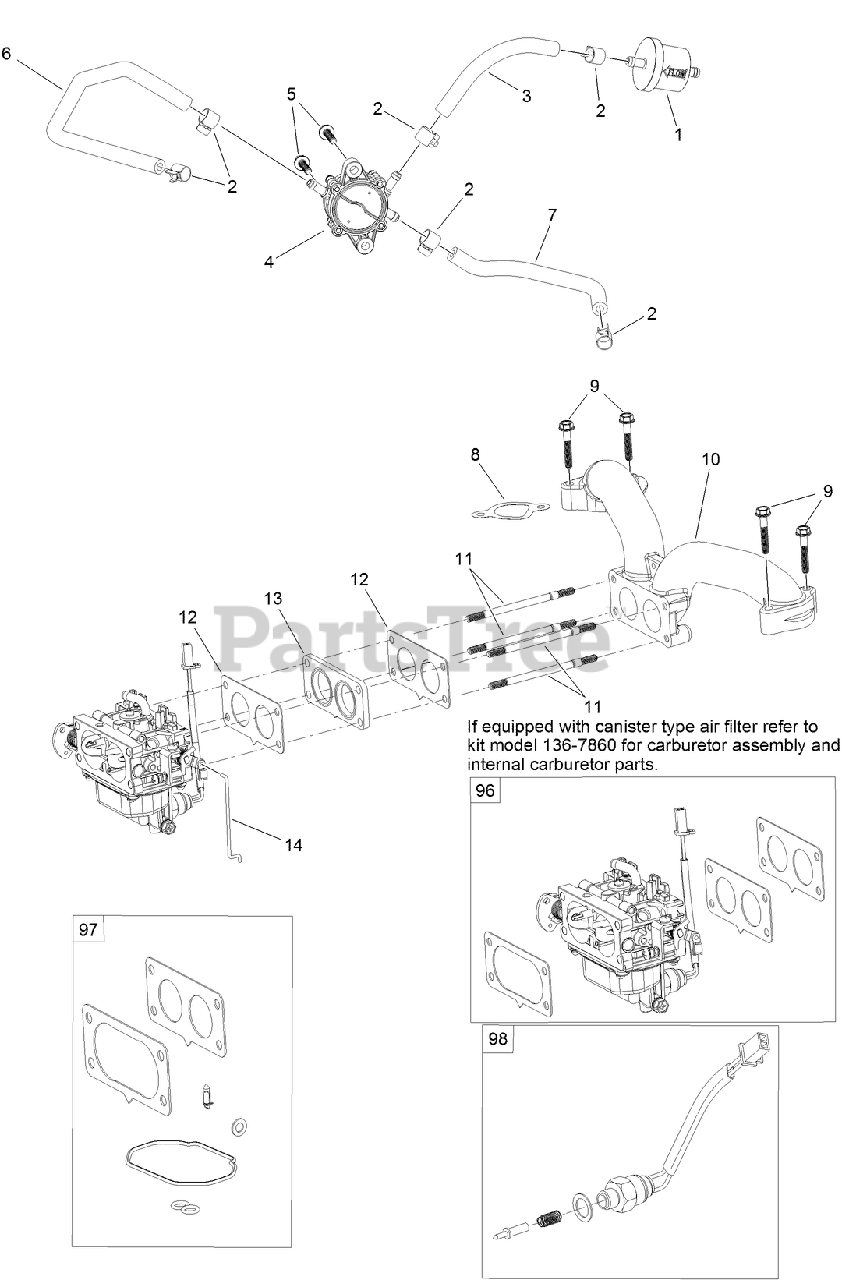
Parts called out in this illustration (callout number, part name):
1	FILTER-FUEL
2	CLAMP-FUEL LINE
3	LINE-FUEL
4	PUMP-FUEL
5	SCREW-HHF
6	HOSE-FUEL
7	HOSE-FUEL
8	GASKET-INTAKE
9	SCREW-HHF
10	MANIFOLD-INTAKE
12	GASKET-CARBURETOR
13	INSULATOR-CARBURETOR
14	LINKAGE-THROTTLE
96	CARBURETOR REPLACEMENT KIT
97	CARBURETOR REPAIR KIT
98	SOLENOID KIT
